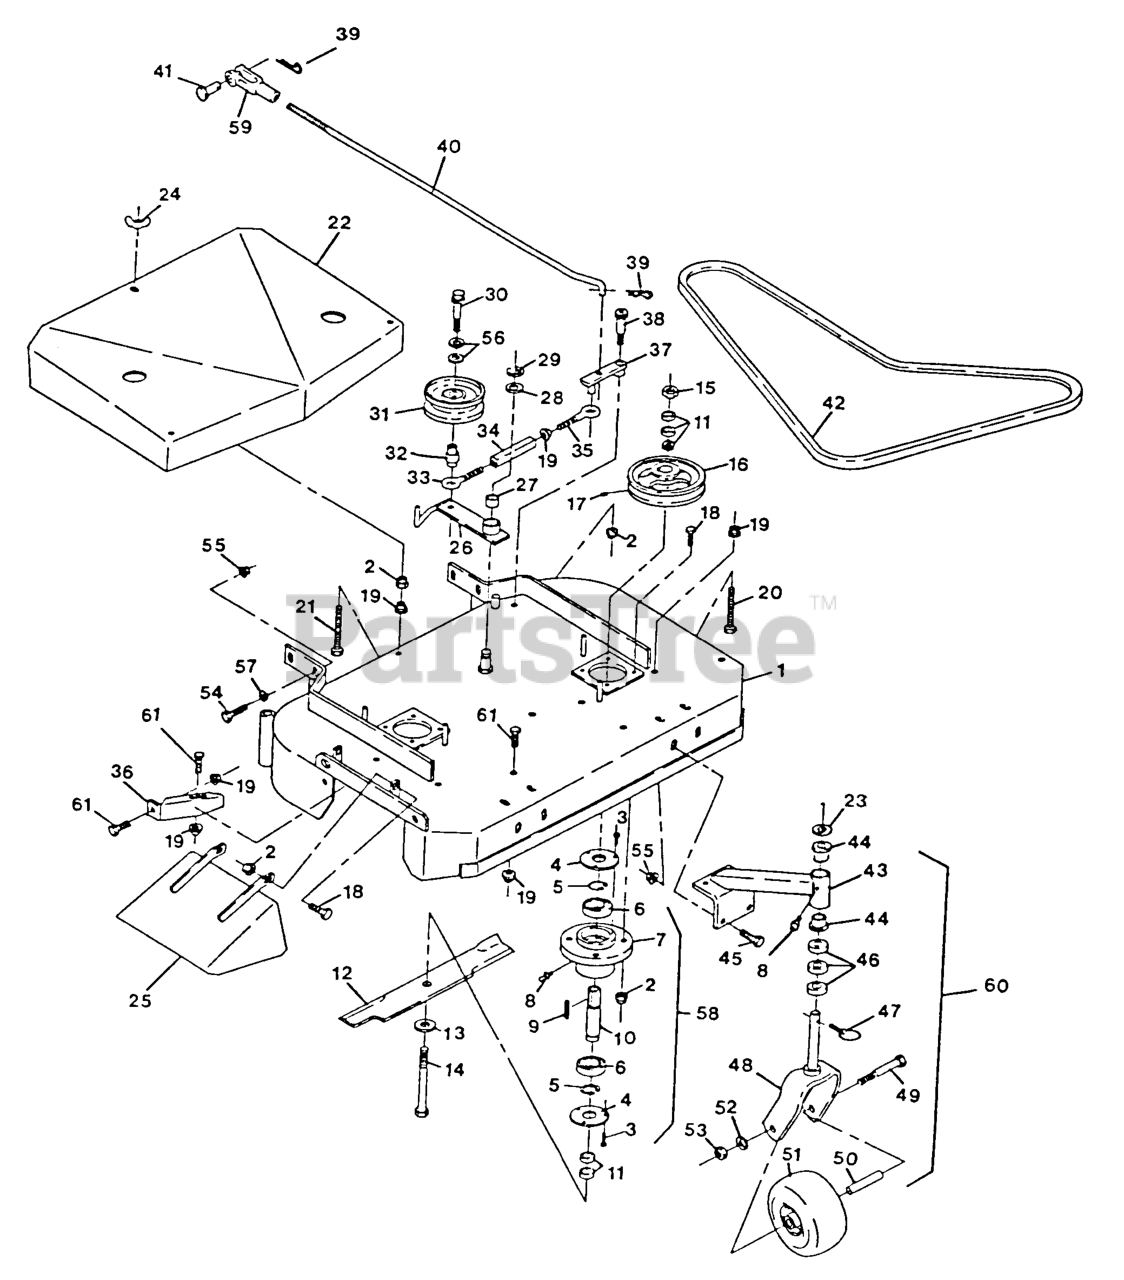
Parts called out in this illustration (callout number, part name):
3	SCRWMACH PHS
4	CAP,CUTTER HOUSING
5	RING,RETNG WLDS 5108-100
7	HOUSING,CUTTER
10	SPINDLE,CUTTER
16	PULLEY,CAST IRON
17	SCREW-SET
20	BOLT,TAP HH
21	BOLTTAP HH
23	WASHER-FLAT
27	BEARING,POWDERED METAL
28	WASHER-SPINDLE
32	BUSHING-ENGAGEMENT
33	EYEBOLT-THREAD, LH
34	BODY-TURNBUCKLE
35	EYEBOLT-THREAD, RH
36	BAFFLE-DOGLEG
38	BOLT,SHLDR KSKH
39	PIN-COTTER
41	PIN-CLEVIS
42	BELT,BLADE DRIVE 36
44	BEARING-FLANGED
46	SPACER-CASTER
58	HOUSING,CUTTER COMPLETE
59	YOKE-ADJUSTABLE
